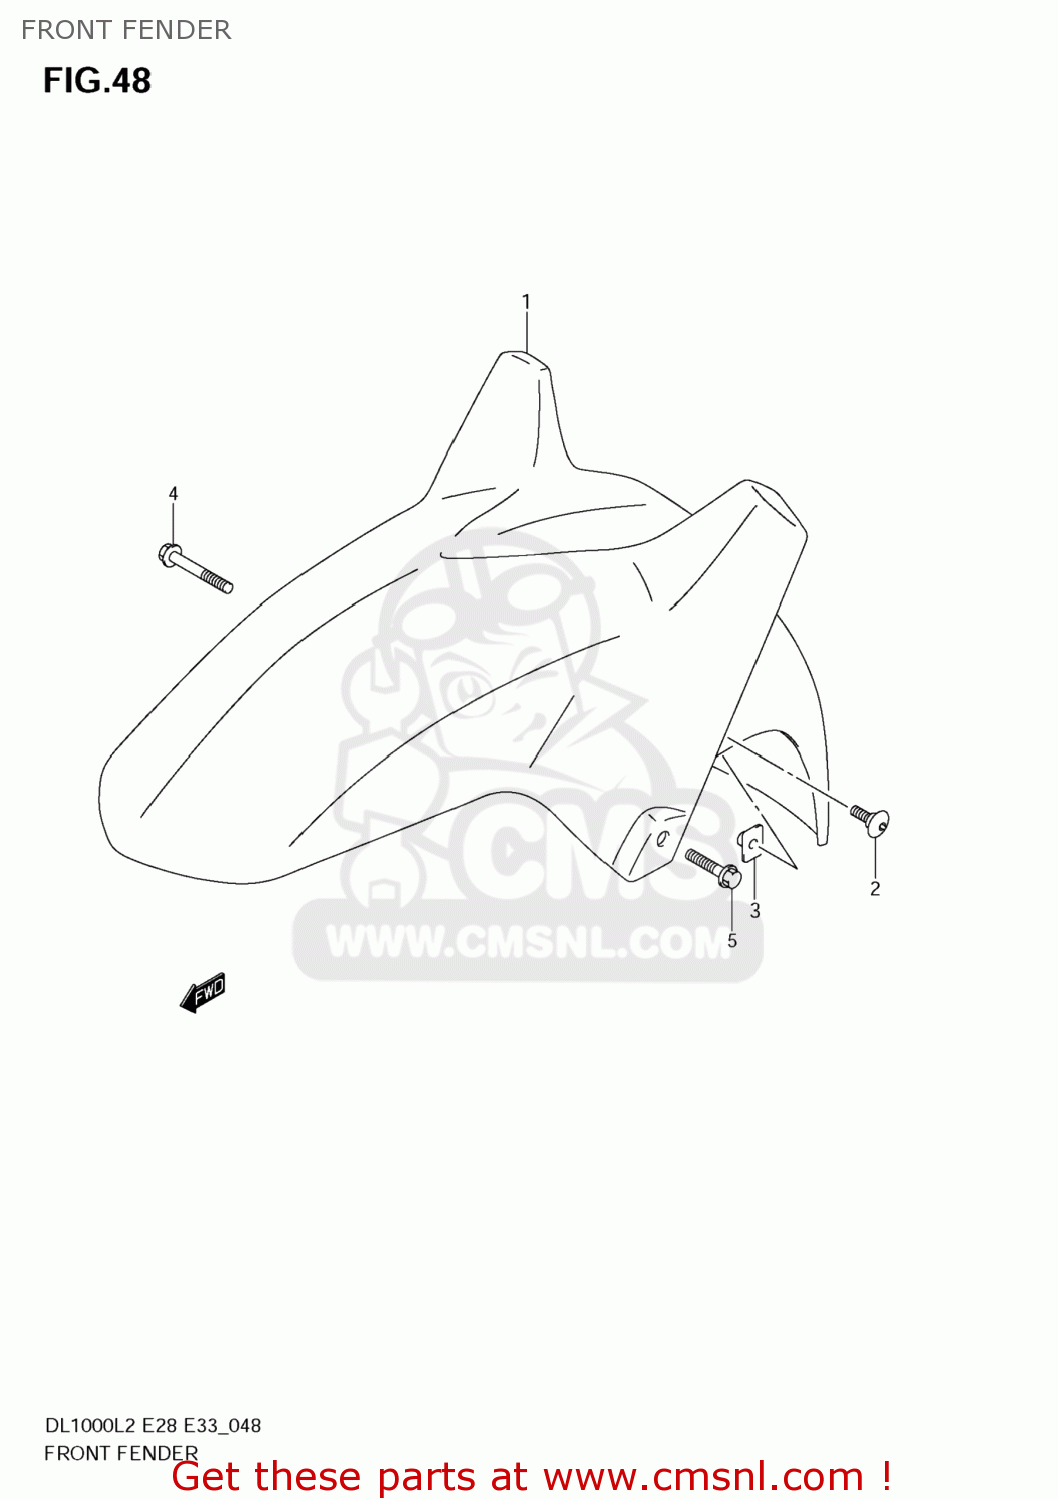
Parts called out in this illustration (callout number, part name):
1	FENDER,FR
2	SCREW(6X16)
3	NUT,FR FENDER
4	BOLT
5	BOLT
